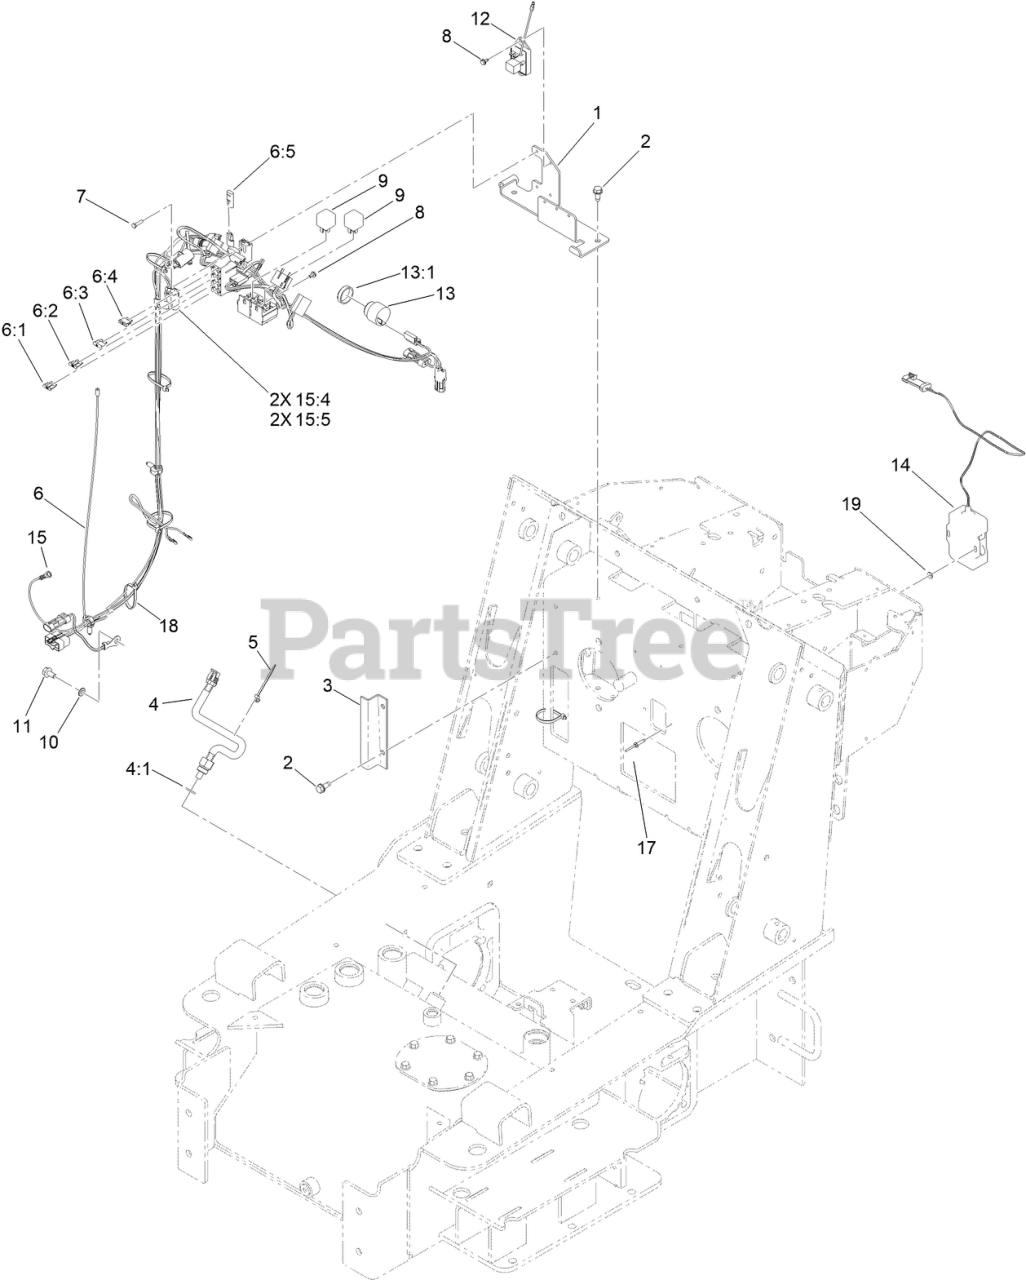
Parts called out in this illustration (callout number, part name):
1	BRACKET-FUSE/RELAY
2	SCREW-THD ROLL, HWH
3	SHIELD-WIRING
4	SWITCH-TEMPERATURE
4:1	O-RING
5	TIE-CABLE
6	HARNESS-WIRE
6:1	FUSE-BLADE, 30 AMP
6:2	FUSE-BLADE, 25 AMP
6:3	FUSE-BLADE, 10 AMP
6:4	FUSE-BLADE, 15 AMP
6:5	CAP-PLUG
7	SCREW
8	SCREW-HWH
9	RELAY
10	WASHER-LOCK
11	SCREW-HHF
12	MODULE-IGNITION DELAY
13	AUDIO ALARM ASM
13:1	NUT-PLASTIC, KNURLED
14	GPS ASM
15	HARNESS-WIRE, GPS
15:4	FUSE-MINI BLADE, 5 AMP
15:5	COVER-FUSE, SINGLE
17	RIVET-POP
18	TIE-CABLE
19	WASHER-PLAIN
